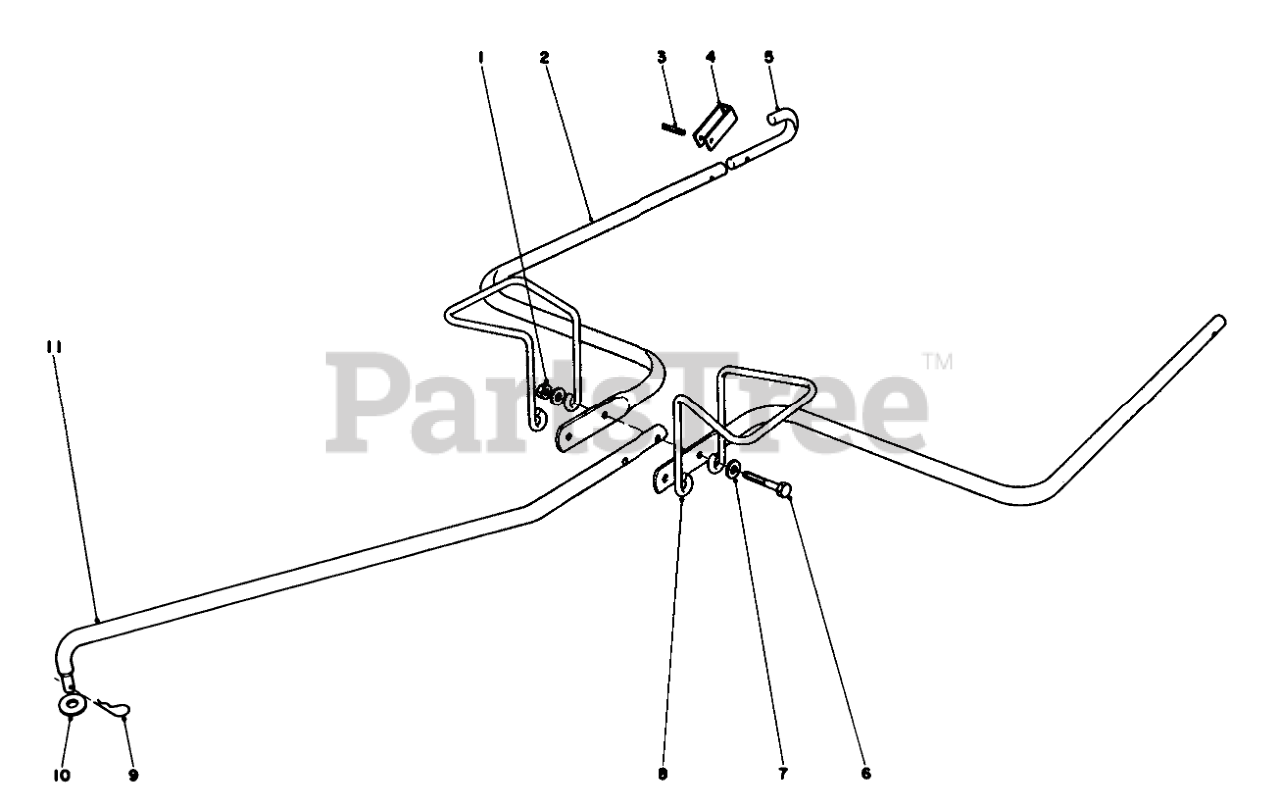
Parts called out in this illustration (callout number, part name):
1	NUT-LOCK, CONE
2	HITCH ARM
3	PIN-ROLL, SLOT
4	HITCH LOCK
5	HOOK HITCH ARM
6	SCREW-HH
7	WASHER-FLAT
8	Support Bag
9	PIN-COTTER
10	PUSH NUT
11	POLE HITCH
